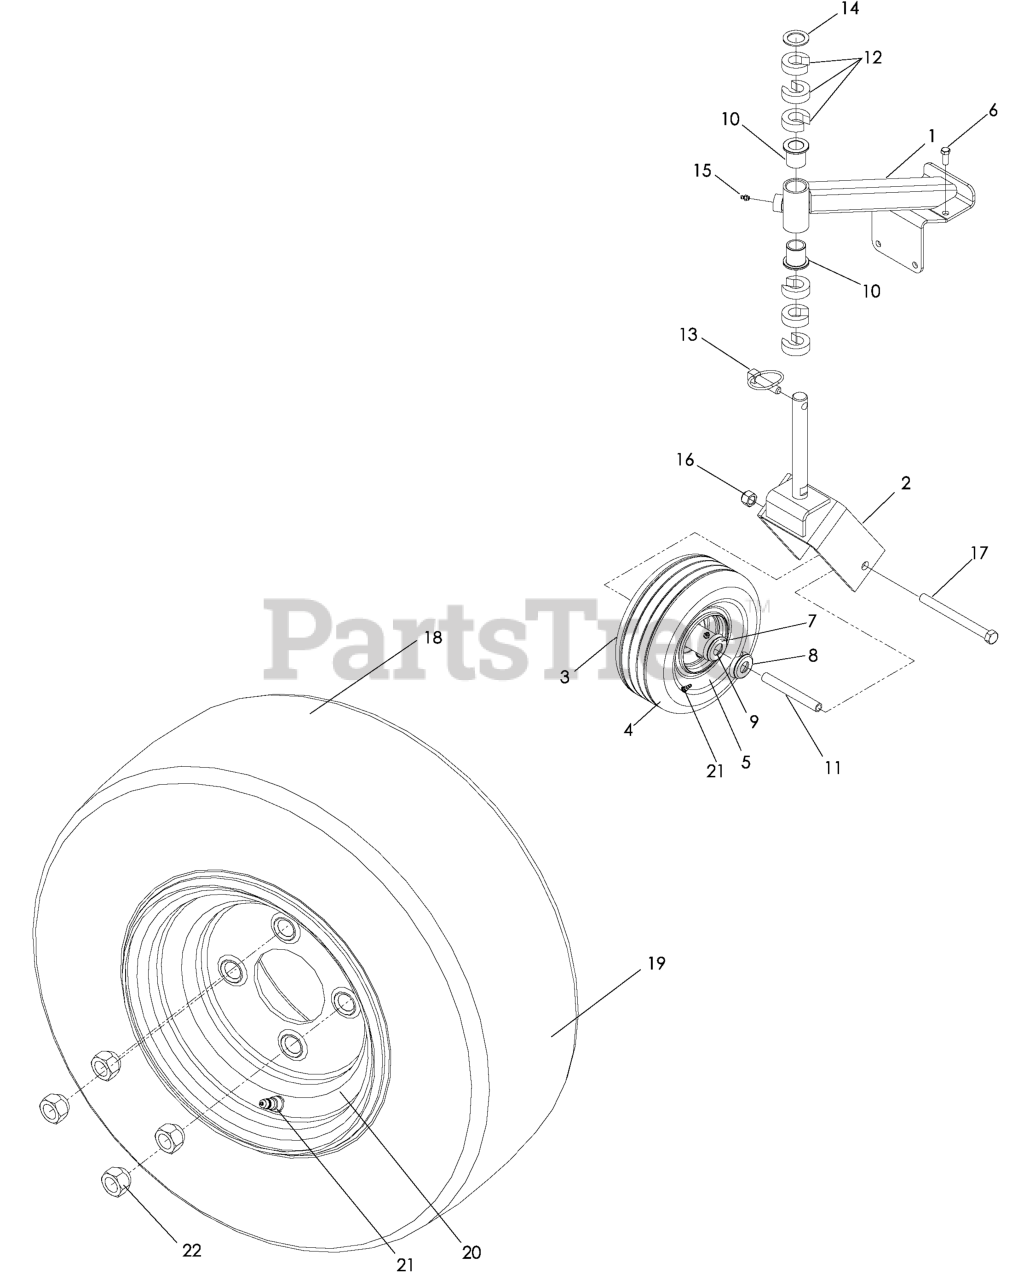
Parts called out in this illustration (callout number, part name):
1	CASTER ARM W/ BUSHING
2	CASTER FORK, ORANGE
3	TIRE/WHEEL.CASTER.9X3.5-4.SMOO
4	TIRE 9 X 3.5 - 4
6	HCS 3/8-16X1.GRD.5.ZD
7	ENDCAP
8	ENDCAP, NOTCHED
9	ROLLER BEARING
10	BUSHING, FLANGED
13	LYNCH PIN 7/16
14	MACHINE BUSHING
15	ZERK
16	NUT 1/2-13 HEX NYLOC ZD
17	HCS 1/2C X 5 1/2
18	TIRE/WHEEL.ASSEM.16X6.5-8.ZTR
19	TIRE, 16/650-8 TURF RIDER
21	VALVE STEM TR-412
22	LUG NUT 1/2F
